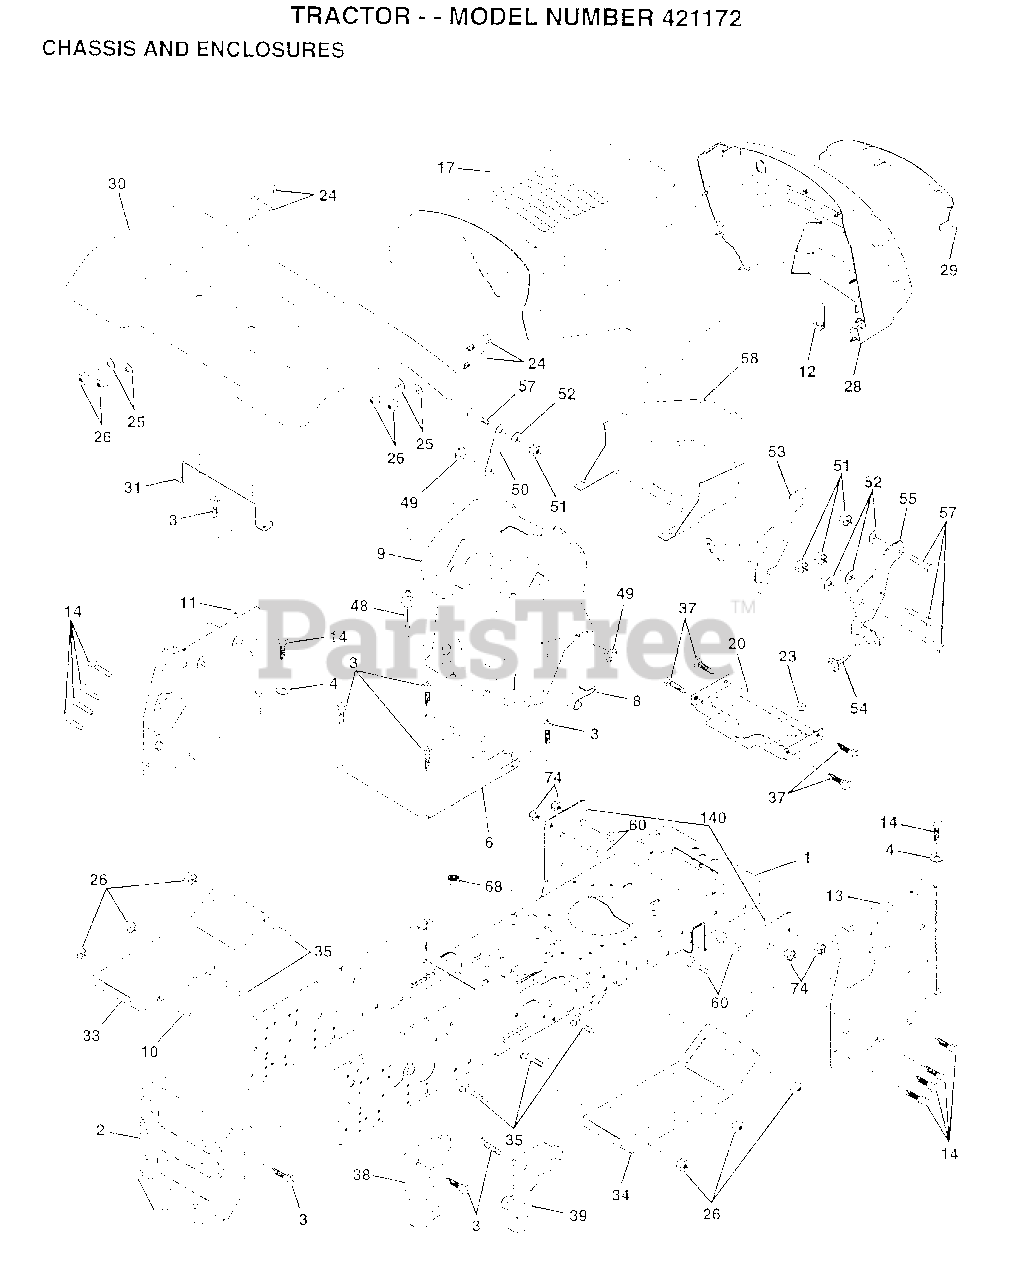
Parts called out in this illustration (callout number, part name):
1	CHASSIS WLDMT 11G
3	SCREW
4	WASHER
8	"CLIP,INSULATOR"
11	PANEL.DASH.LH.
12	CLIP.TINNERMAN
13	PANEL.DASH.RH
14	SCREW LT
20	PLATE.MTG.BTRY.TK
24	BOLT
25	WASHER
26	NUT
28	GRILL.P/L.EURO.
29	LENS.EURO.W/DECAL
31	BRKT FENDER
33	FOOTREST.LH.LT/GT
34	FOOTREST.RH.LT/GT
35	BOLT
37	SCREW LT
38	BRACKET ASM LH
39	BRACKET ASM RH
48	RIVET.PUSH.PLATE
49	SCREW HEX CRT
50	BRACE SUPT DASH
51	NUT
52	WASHER
53	BRACKET.GRILLE.LH
55	BRACKET.GRILLE.RH
58	DUCT.AIR.B&S.18HP
60	BOLT
68	NUT
